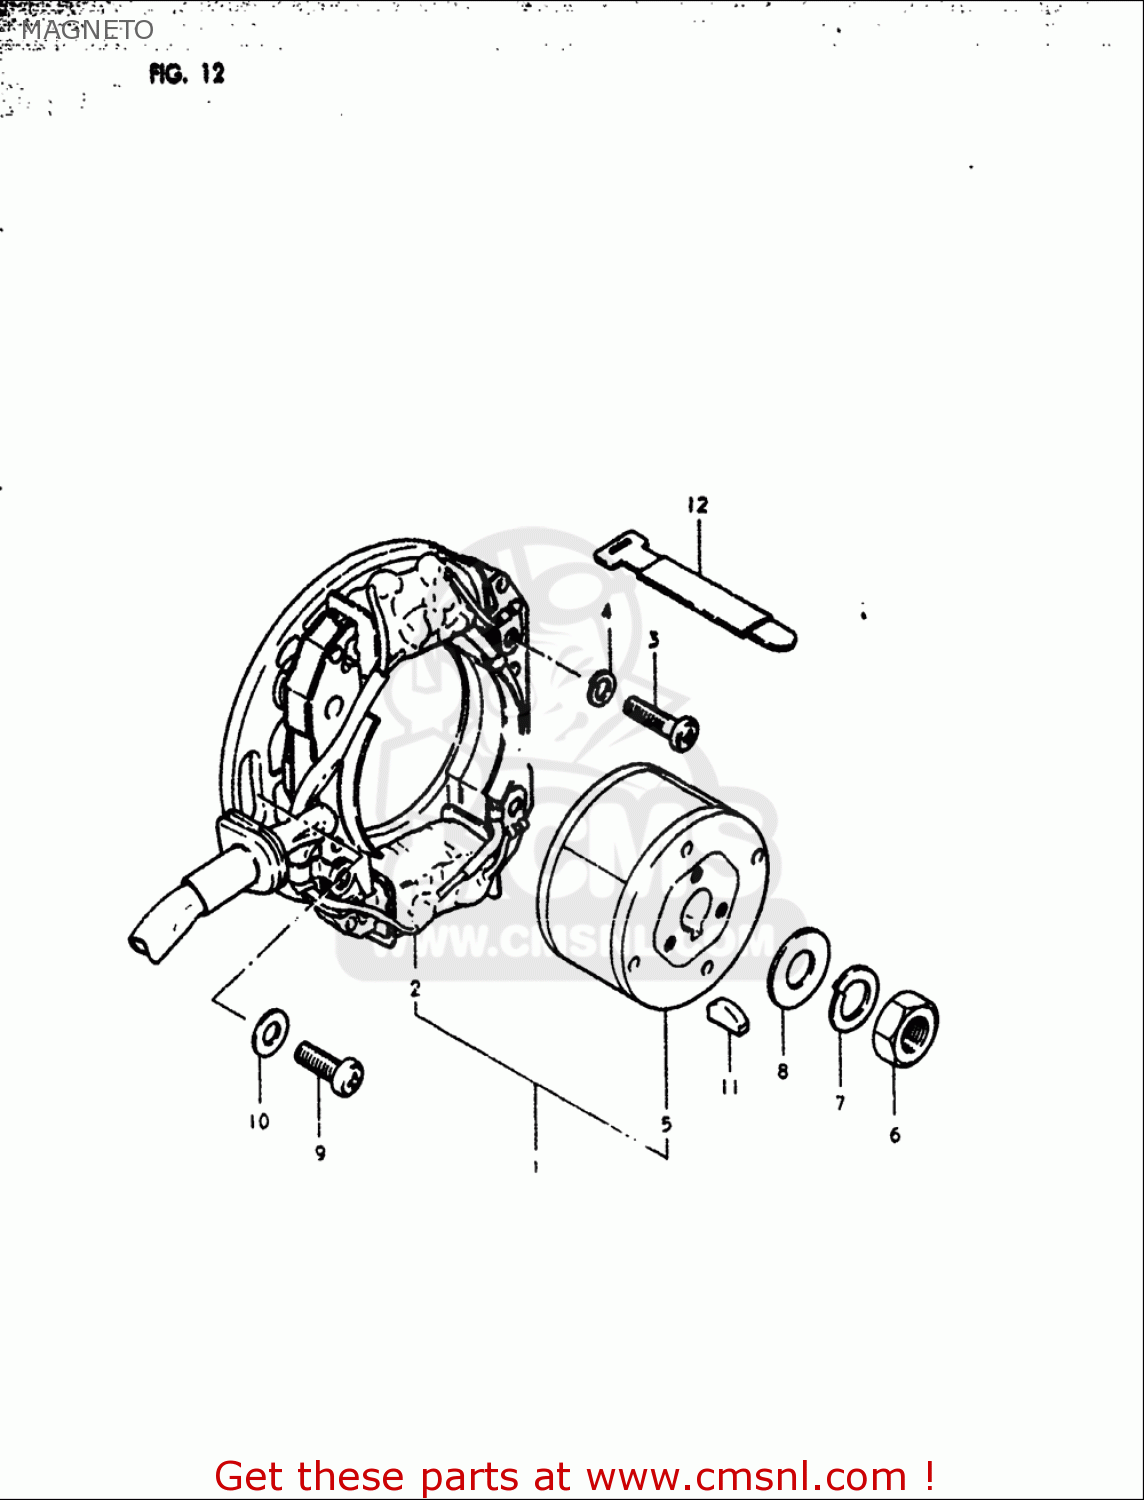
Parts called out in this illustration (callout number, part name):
2	STARTER ASSY
3	SCREW
4	WASHER,LOCK
6	NUT
7	WASHER,LOCK
8	WASHER
9	SCREW
10	WASHER
11	KEY
12	CLAMP
